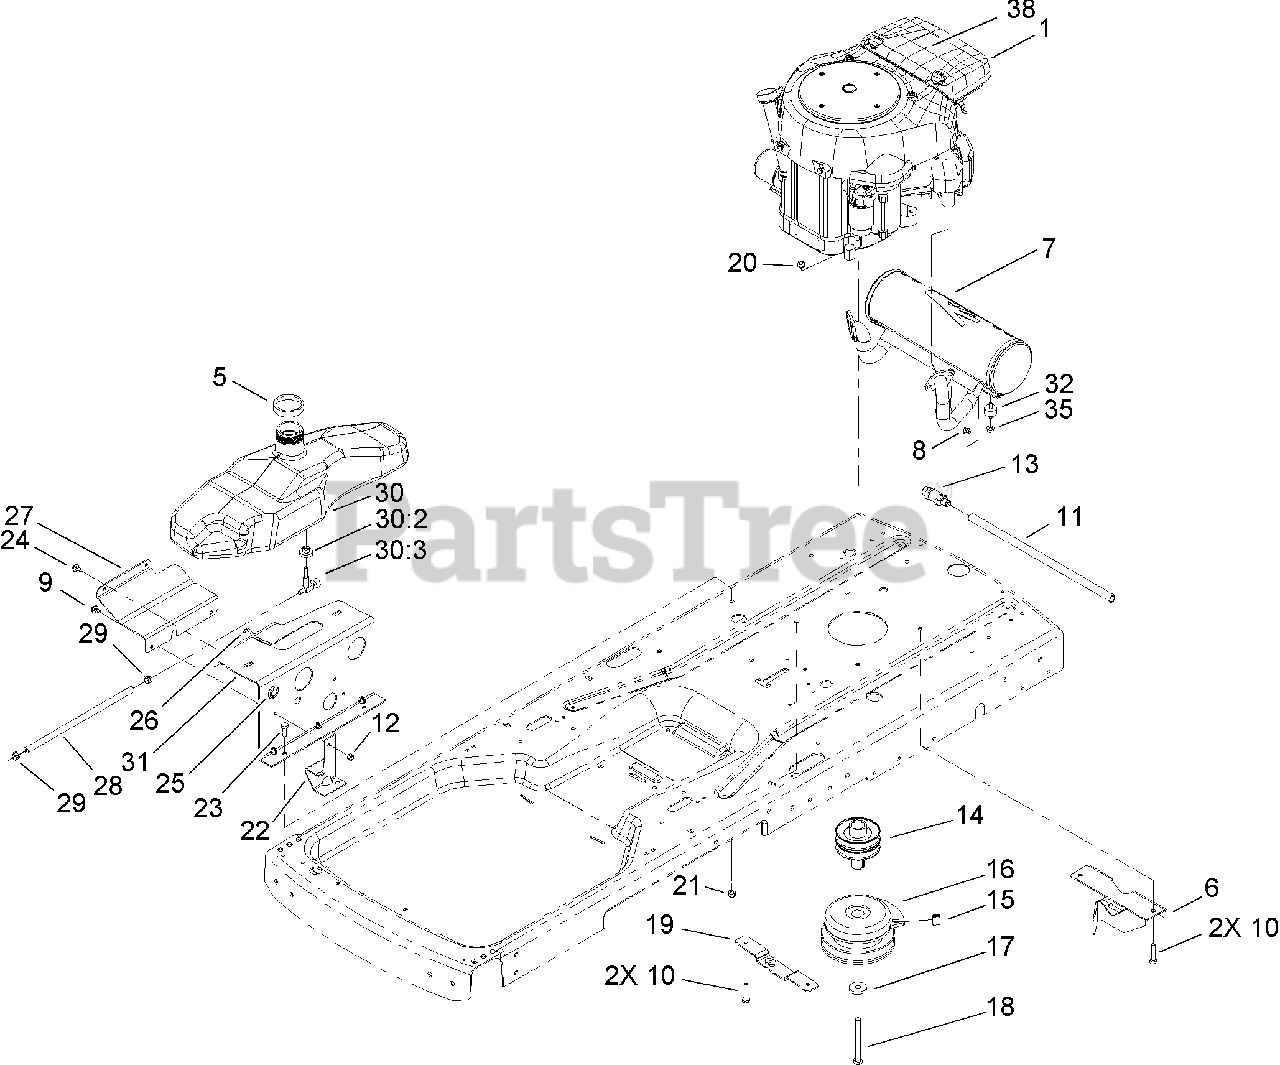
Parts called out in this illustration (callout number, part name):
5	SEAL-FOAM
6	BRACKET-PIVOT
9	SCREW-HWH
10	SCREW-HH
11	TUBE-DRAIN, OIL
12	NUT-LOCK, NI
13	VALVE-DRAIN, OIL
14	PULLEY-ENGINE
16	CLUTCH-PTO, ELECTRIC
18	SCREW-HH
19	PLATE-MOUNT, IDLER
21	NUT-LOCK, NI
22	MOUNT-SPRING
23	SCREW-HH
24	SCREW-HHF
27	PLATE-SUPPORT
28	HOSE-FUEL
30	FUEL TANK ASM
30:3	VALVE-FUEL
32	ISOLATOR-RUBBER
38	DECAL-ENGINE
